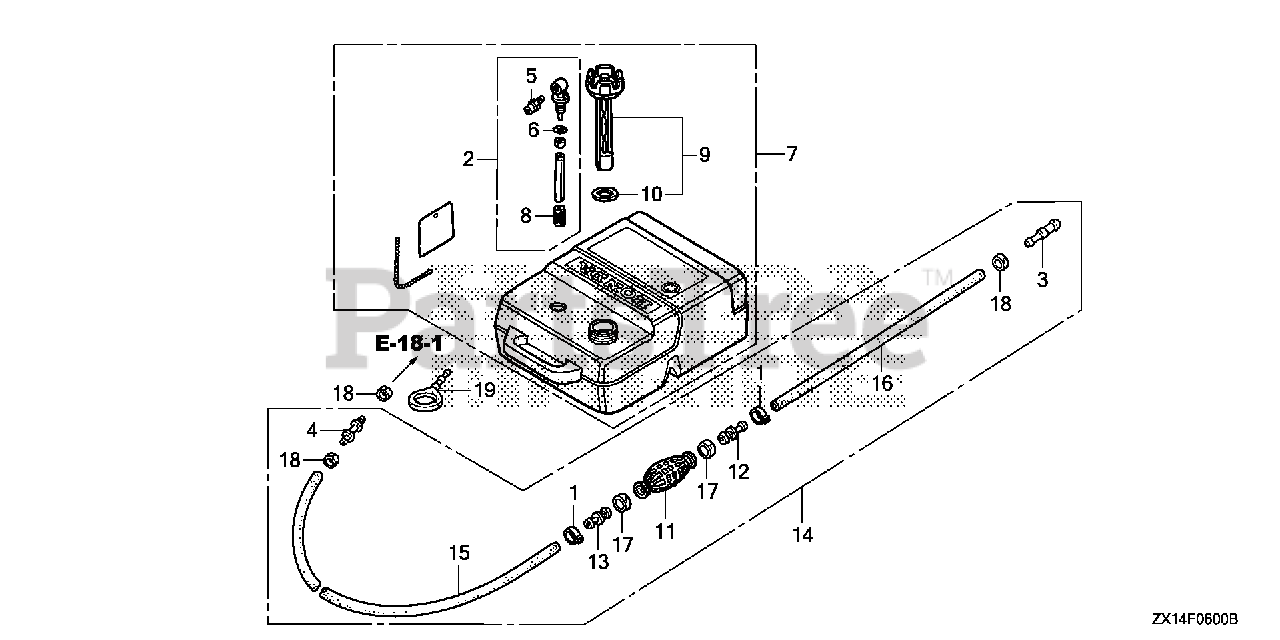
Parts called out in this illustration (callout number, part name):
1	CLAMP, FUEL TUBE (CONNECTOR TYPE)
2	JOINT ASSY., FUEL Use from Frame SN 1300962.
3	JOINT, FUEL TUBE (JOINT TYPE)
4	JOINT, FUEL TUBE
5	FITTING, QUICK DISCONNECT Use from Frame SN 1205705.
6	O-RING Use from Frame SN 1300962.
7	TANK ASSY., FUEL
8	FILTER, FUEL
9	CAP, FUEL FILLER
10	GASKET, FUEL CAP
11	BULB, PRIMER
12	VALVE, IN.
13	VALVE, OUTLET
14	TUBE ASSY., FUEL TANK (JOINT TYPE)(FKM)
15	TUBE, FUEL LONG (7.3X2000) (CONNECTOR TYPE)
16	TUBE, FUEL SHORT (7.3X500) (CONNECTOR TYPE)
17	BAND, TUBE CLIP (20MM)
18	BAND, TUBE CLIP (12.5MM)
19	PLUG, FUEL TUBE
